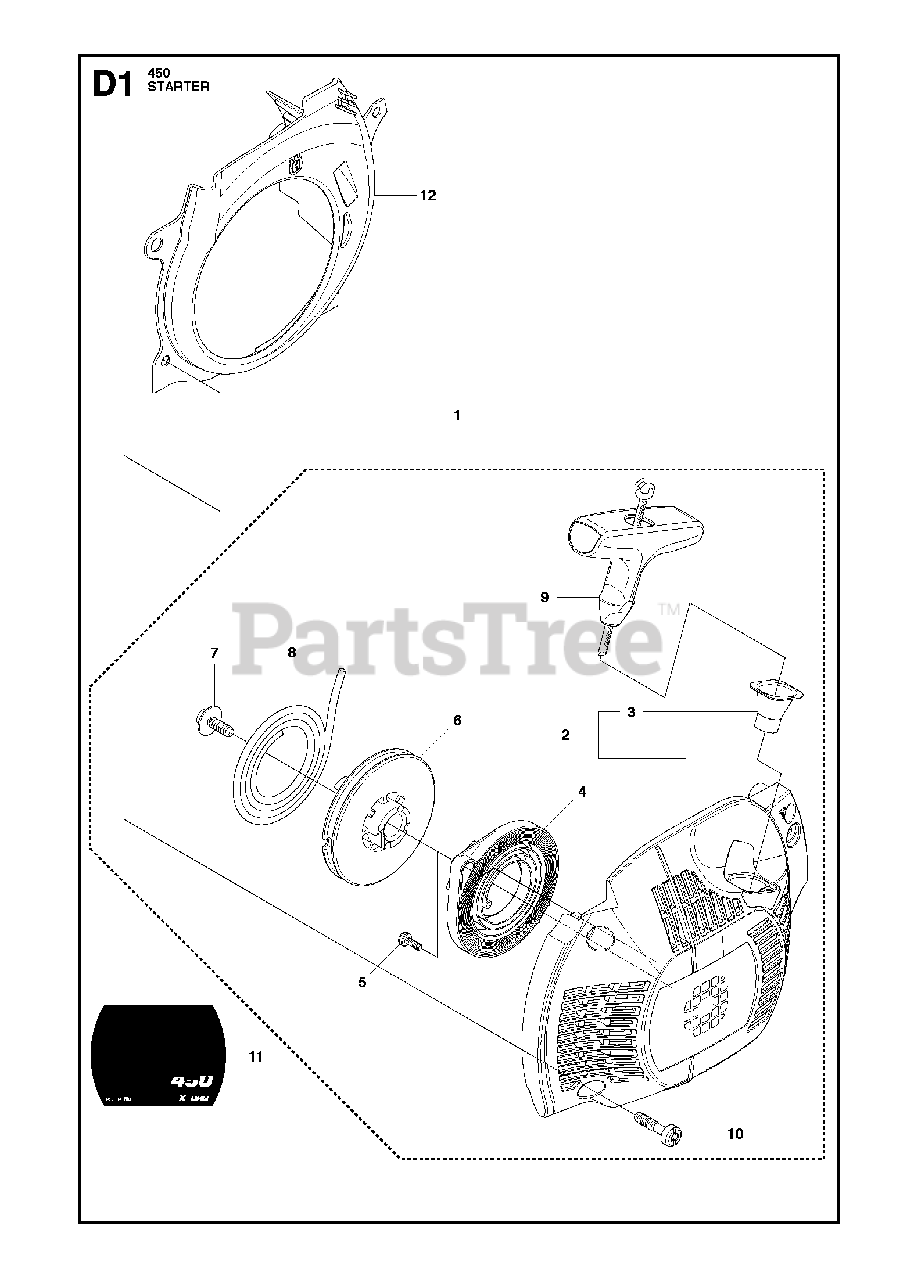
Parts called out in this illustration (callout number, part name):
1	STARTER ASSY
2	STARTER HOUSING
3	SLEEVE
4	SPRING CASSETTE ASSY
5	SCREW
6	PULLEY
7	SCREW
8	STARTER ROPE
9	HANDLE
10	SCREW
12	COOLING AIR CONDUCTOR
